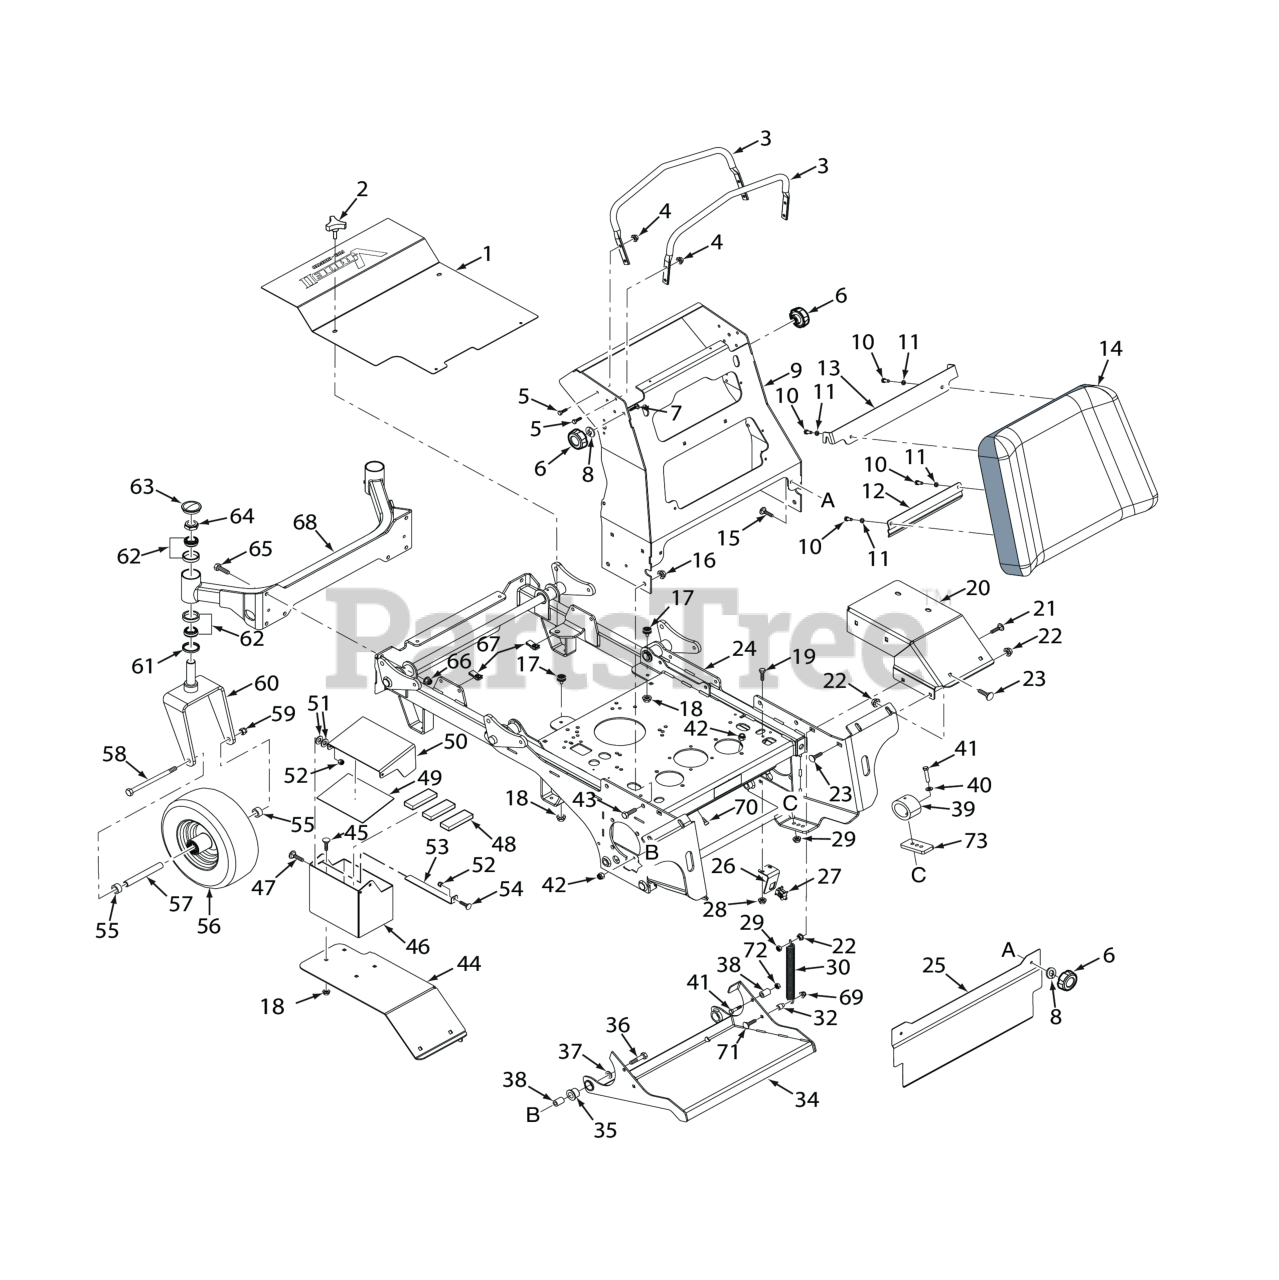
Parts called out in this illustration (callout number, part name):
1	Belt Cover w/Decals
2	Knob, w/stud 3/8-16 x 1-1/4"
3	Reference Bar
4	Nut, Serrated Flange 5/16-18 (Right Front Engine Mounting, Briggs and Kohler Only)
5	BOLT, SERRATED FLANGE HEX HEAD 5/16-18 X 3/4"
6	Knob, 5/16-18
7	Bolt, Carriage 5/16-18x1" (large frame units only)
8	Nut, Push-On 5/16-18
9	Handlebar Weldment, SVRII
10	BOLT, SERRATED FLANGE HEX HEAD 5/16-18 X 3/4"
11	Lockwasher, 5/16 (.317 x .586 x .078) Helical Spring
12	Bracket, Knee Pad - Lower
13	Bracket, Knee Pad - Upper
14	Operator Pad Assy, SVRII (INCL. 10,11,12,13)
15	Bolt, 5/16-18 x .75 RHSN Carriage
16	Locknut, 1/2-13 Spiral Lock
17	Bumper, Rubber 5/16-18 x 5/8"
18	Nut, Serrated Flange 5/16-18 (Right Front Engine Mounting, Briggs and Kohler Only)
19	BOLT, HEX HEAD, 1/4-20 X 3/4 GR.5
20	Fender, RH
21	Bolt, RDHD Carr. 3/8-16 x 1-1/2 (52" & 61")
22	NUT, 3/8-16 SERRATED FLANGE HEX HEAD
23	Bolt, Carriage 3/8-16 x 3/4"
24	Mainframe Assy. - SVRII
25	Guard, Foot -SVRII
26	Switch Bracket, Operator Presence
27	SWITCH, NEUTRAL INTERLOCK
28	NUT, 1/4-20 SERRATED FLANGE HEX HEAD
29	Nut, Flange Elastic Stop Nut, 3/8-16
30	Spring,Counter Balance
31	Bolt, Hex Head 5/16-18 x 1-1/2" (Right Front Engine Mounting, Briggs and Kohler Only)
32	Spacer, Pump Dampener
33	HEX NUT, ELASTIC STOP LOCK, 5/16-18
34	Footplate Assy, SVRII (Incl. #35)
35	Bearing, .750 I.D. Plastic
36	Capscrew, Hex Head 3/8-16 x 2.0"
37	Flatwasher, 3/8" Special (.391 x .938 x .105)
38	Yoke, Front Caster Wheel
39	Isolator, Footplate
40	Flatwasher, 3/8 (.406 x .812 x .065)
41	Bolt, Hex Head 3/8-16 x 1-3/4" (Kohler EFI)
42	HEX NUT, ELASTIC STOP LOCK, 3/8-16
43	Capscrew, 1/2-13 x 1" Serrated Flange Hex Head
44	Fender, LH
45	Bolt, 5/16-18 x .75 RHSN Carriage
46	Battery Box, Lower
47	BOLT, HEX HEAD, 1/4-20 X 3/4 GR.5
48	PAD, BATTERY SUPPORT
49	Insulation, Battery Cover (Gas Only)
50	Battery Box, Upper
51	Flatwasher, 1/4" (.312 x .750 x .065")
52	HEX, NUT, ELASTIC STOP LOCK, 1/4-20
53	Battery Box Latch
54	Serr. Fl. Hex Head CPSCR, 1/4-20 x 3/4"
55	Spacer, Caster Wheel
56	Wheel Assy, 61V, 72V (Incl. 20, 54, 55)
57	Sleeve, Caster Wheel (61V, 72A/VS)
58	Bolt, Hex Head 1/2-13 x 9-1/2" (61V & 72A/VS)
59	HEX LOCKNUT, ELASTIC STOP, 1/2-13
60	Yoke Weldment, (Black))
61	Seal, 2.00" O.D. x 1.625" Bore
62	Bearing Set
63	Cap, Grease
64	Nut, Elastic Stop 1.0"-14
65	BOLT, HEX HEAD, 7/16-14 X 1-1/4
66	Nut, 7/16-14 Flange Elastic Stop
67	U-Nut, 3/8-16
68	Caster Support Weldment (61)
69	Nut, Flange Head Elastic Stop 5/16-18
70	BUMPER, PLUG
71	Bolt, Carriage, 5/16-18 x 1½"
72	Bolt, Hex Head 3/8-16 x 1" Ser. Flg.
73	Riser
